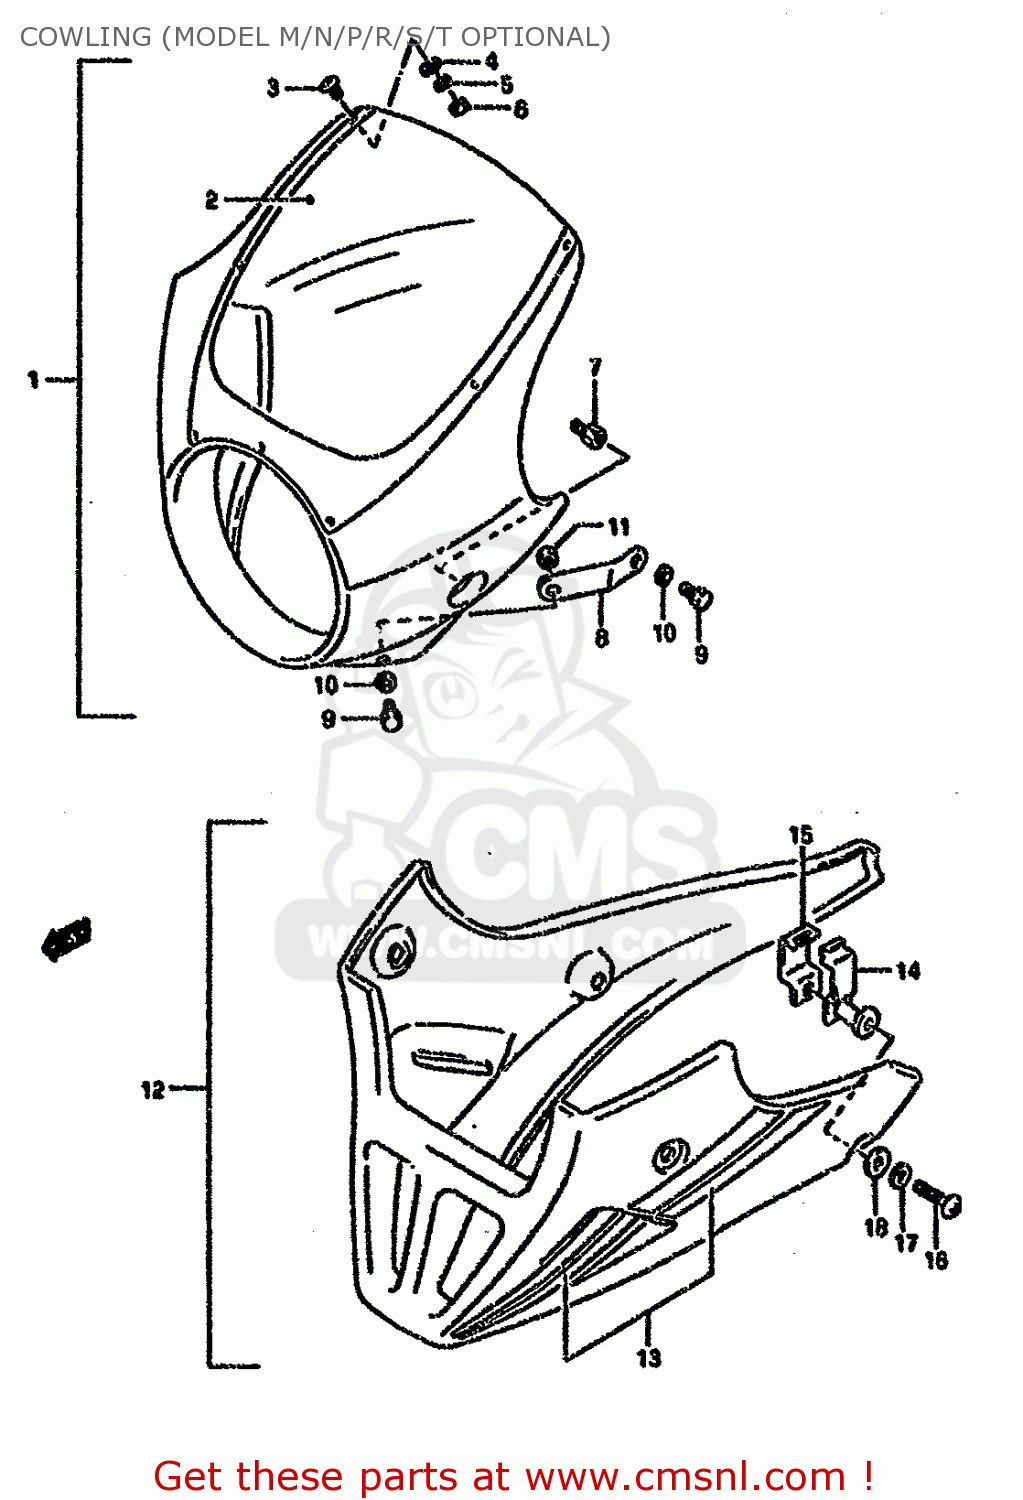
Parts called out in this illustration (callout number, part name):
1	COVER SET,UPPER COWLING
2	SCREEN,COWLING
3	SCREW
4	WASHER
5	WASHER,LOCK
6	NUT
7	BOLT,UPR COWLING HEADLAMP
8	BRACE,UPR COWLING
9	BOLT
10	WASHER,LOCK
11	NUT 6MM
12	COVER SET,UNDER COWLING
13	TAPE SET,UNDER COWLING
14	BRACKET,UNDER COWLING OUTER
15	BRACKET,UNDER COWLING INNER
16	SCREW
17	WASHER,LOCK
18	WASHER(6.5X18X1.6)
24	COWLING SET,UNDER (BLUE)
25	TAPE SET
26	BRACKET,UNDER COWLING OUTER
27	BRACKET,UNDER COWLING INNER
28	SCREW
29	WASHER,LOCK
30	WASHER
